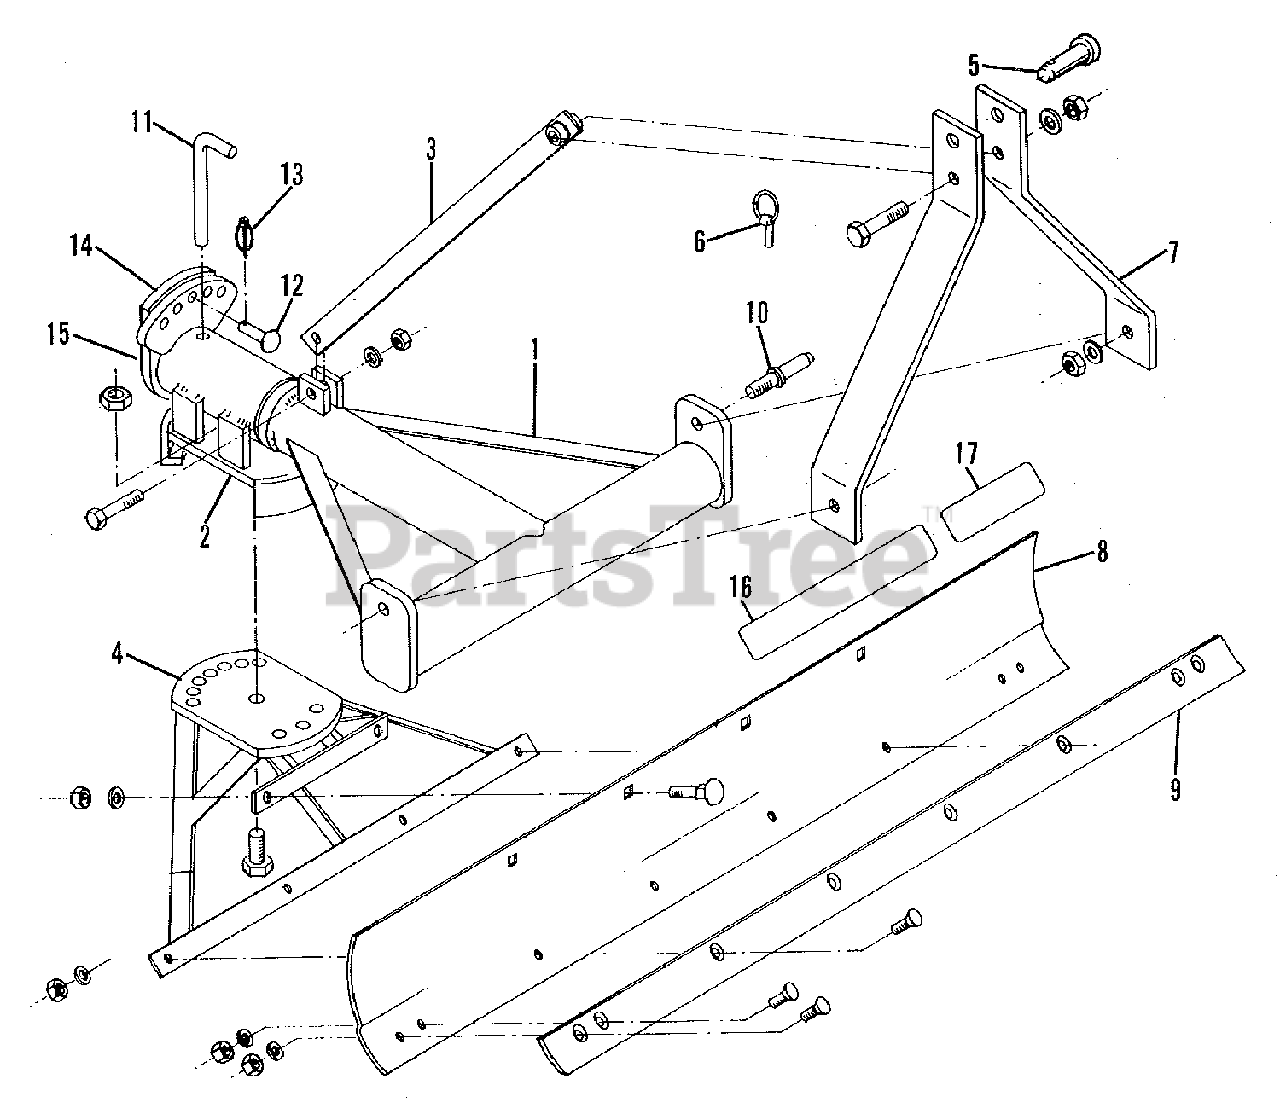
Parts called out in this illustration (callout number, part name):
1	FRAME ASSEMBLY, Upper
2	FRAME ASSEMBLY, Swivel
3	BRACE ASSEMBLY
3	CAPSCREW, 5/8NC x 4
3	CAPSCREW, 5/8NC x 2-1/2
3	LOCKWASHER, 5/8
4	FRAME ASSEMBLY, Moldboard
4	CAPSCREW, 1"NC x 2-1/2
4	NUT, Lock, 1"NC x 2-1/2
5	PIN, Hitch, Upper
8	BOLT, Carriage, 5/8NC x 1-3/4
8	LOCKWASHER, 5/8
9	BLADE, Cutting
9	BOLT, Plow, No. 3 Head, 5/8NC x 1-3/4
9	LOCKWASHER, 5/8
10	PIN, Link (Cat. 1)
10	LOCKWASHER, 7/8
14	BAR, Pivot (Welded)
15	COLLAR (Welded)
16	DECAL (Allis-Chalmers)
17	DECAL (46 Model Identification)
